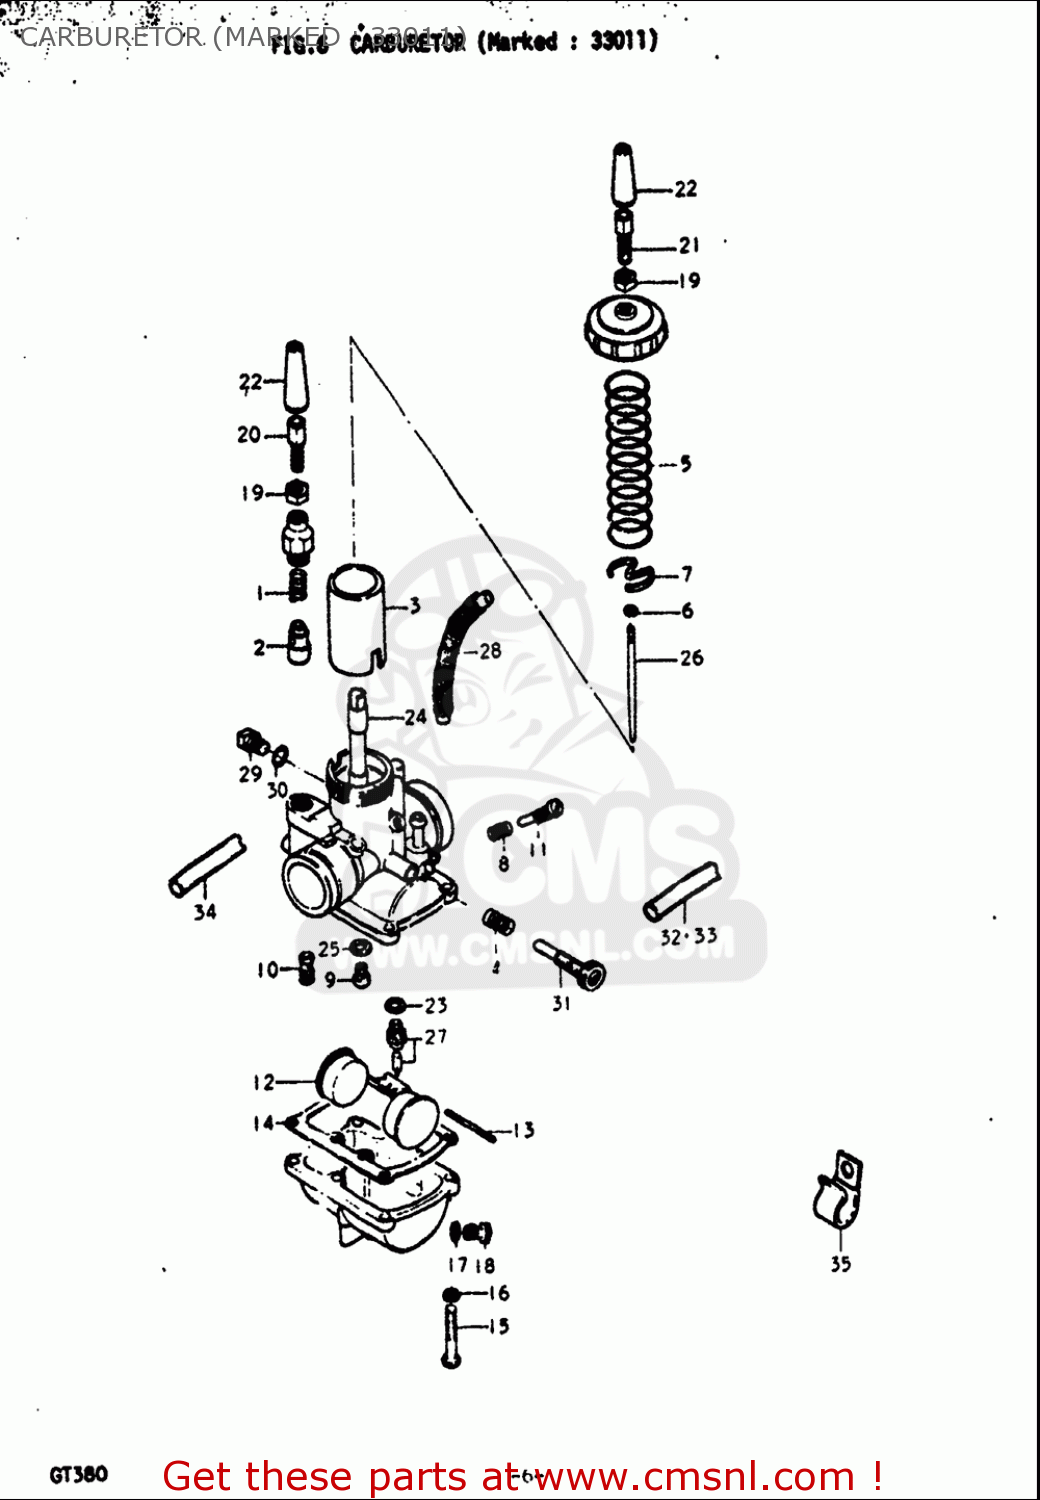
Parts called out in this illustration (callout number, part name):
1	SPRING
2	PLUNGER,STARTER
4	SPRING
6	CLIP
7	SEAT,THROTTLE VALVE SPRING
8	SPRING
9	JET,MAIN
10	JET,PILOT(22.5)
11	SCREW,PILOT AIR
12	FLOAT
13	PIN,FLOAT
14	GASKET,FLOAT CHAMBER (NAS)
15	SCREW 4X16
16	WASHER,LOCK
17	GASKET,DRAIN,PLUG (NAS)
18	PLUG
19	NUT
20	ADJUSTER,CABLE
22	CAP,RUBBER
23	GASKET,VALVE SEAT (NAS)
25	WASHER
26	NEEDLE,JET
27	VALVE ASSY,NEEDLE
29	BOLT
30	GASKET,THRO VALVE INSPECTION (NAS)
32	HOSE(3X5X600)
35	CLAMP
